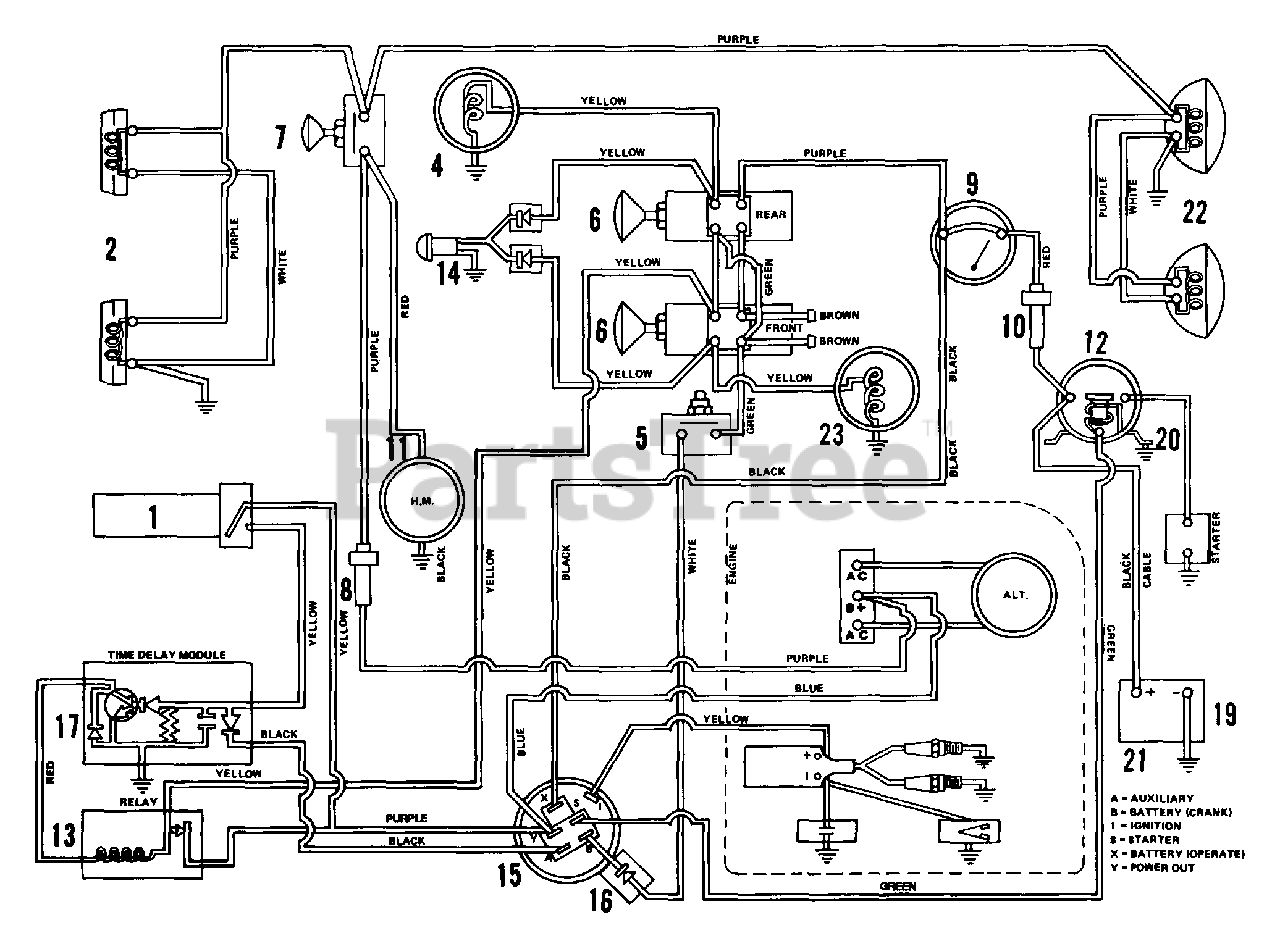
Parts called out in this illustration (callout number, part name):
1	SWITCH SEAT
2	TAIL LIGHT ASSEMBLY W/BULLET
2	TAIL LIGHT LENS
2	MALE DISCONNECT ADAPTER
2	SCR-MCH 10-24X.50 SLTR PL
2	WSHR-LK 10X.047 MED PL
2	NUT-HEX 10-24 PL
4	ELECTRIC CLUTCH
5	SAFETY SWITCH
5	CONNECTOR
5	NUT-HEX .625-32 PL
6	CLUTCH SWITCH
6	CONNECTOR
6	WSHR-FL-STL .382X.812X.023 PL
7	LIGHT SWITCH
7	CONNECTOR
7	WSHR-FL-STL .382X.812X.023 PL
8	7 Amp Fuse
9	AMMETER
9	WSHR-LK-EXT #10 ID X .022
9	NUT 10-32 PL
10	30 Amp Fuse
12	SOLENOID
12	WSHR-LK-EXT #10 ID X .022
12	NUT 10-32 PL
12	WSHR-LK-INT .313X.030 PL
12	NUT-JAM .312-24 PL
12	BLT-HEX .25-20X.75 PL GR2
12	BLT-HEX .25-20X1.00 GR2
12	WSHR-FL-STL.281X.62X.065 PL
12	WSHR-LK-EXT. 250 ID
13	RELAY
14	PTO INDICATOR LIGHT
14	LAMP SOCKET
14	SPEED NUT
15	SWITCH ASSEMBLY
15	CONNECTOR HOUSING
15	WSHR-LK-INT .563X.040 PL
15	NUT .562-24
16	DIODE ASSEMBLY
16	SCR-TAP .250-20X.50 HXSLHDPL
17	TIME DELAY MODULE
17	SCR-MCH 10-24X.50 SLTR PL
17	WSHR-LK 10X.047 MED PL
17	NUT-HEX 10-24 PL
19	GROUND CABLE .25X6.50X.31
19	BATTERY CABLE
19	WSHR-LK .250X.077 HVY PL
19	NUT-HEX .250-20 PL
20	STARTER CABLE .25X.35.25X.31
20	GROUND CABLE
21	BATTERY
22	HEAD LIGHT
22	HEAD LIGHT RETAINER RING
22	SCR-MCH 10-24X.50 SLTR PL
22	WSHR-FL-STL .250X.562X.049 PL
23	DIESEL CLUTCH ASSEMBLY
23	CLUTCH ASSEMBLY 1 1/8 BORE
23	CLUTCH ASSEMBLY 1-1/4 BORE
27	CONNECTOR
